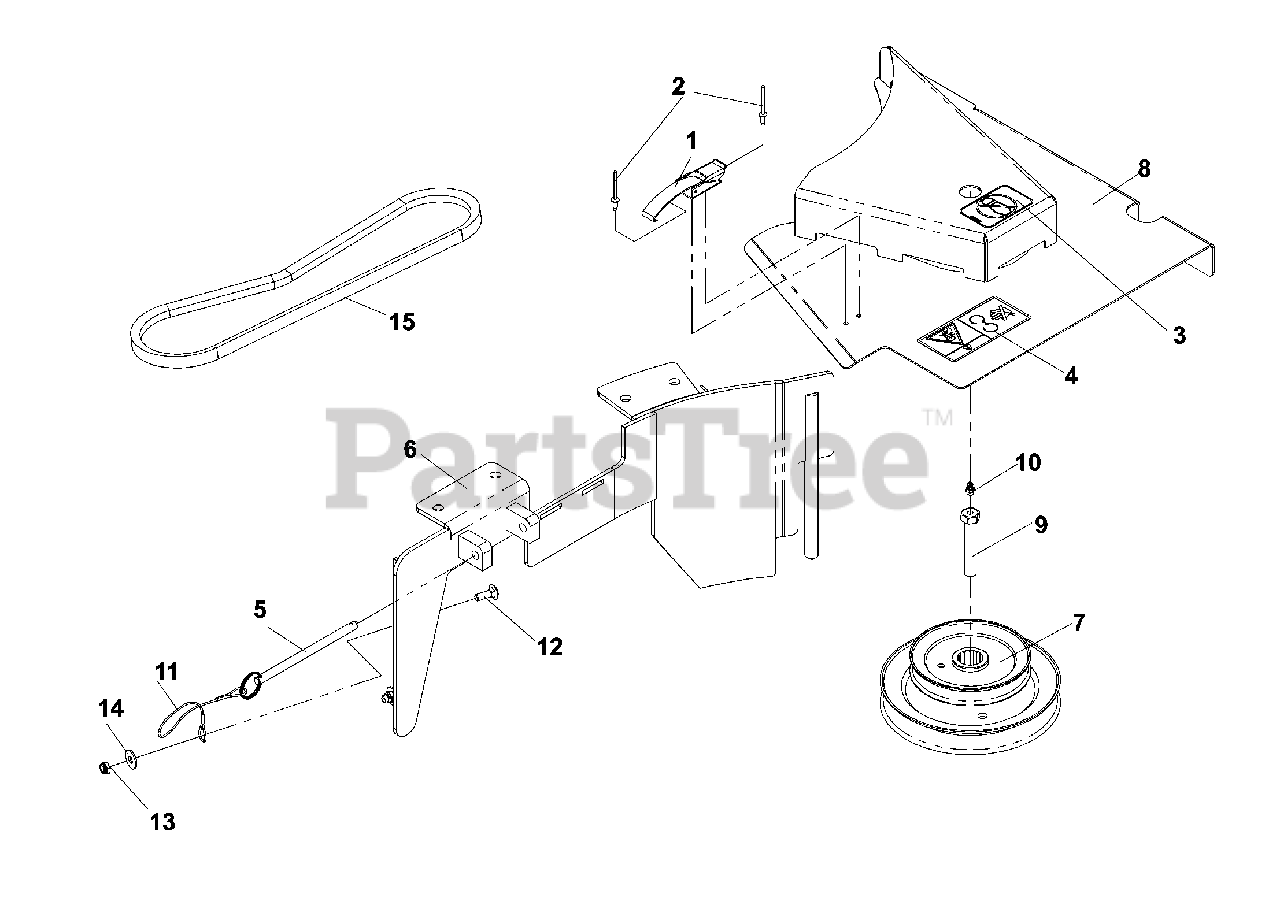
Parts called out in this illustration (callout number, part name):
1	DRAW LATCH
2	RIVET, BLIND, DOME STYLE, 5/32 DIA.
3	DECAL, NO STEP
4	DECAL, DANGER BELT DRIVES
6	BLOWER DECK PLATE, 61
7	PULLEY, STACKED DOUBLE, 61
8	BELT SHIELD W/DECALS & LATCH, 61
9	HCS, 7/16-20 X 2 1/2, GR5, SPEC.
10	ZERK
12	RHSNB, 1/4-20 X 3/4, GR2
13	WASHER, 1/4
14	NUT, 1/4C, THIN NYLOC
